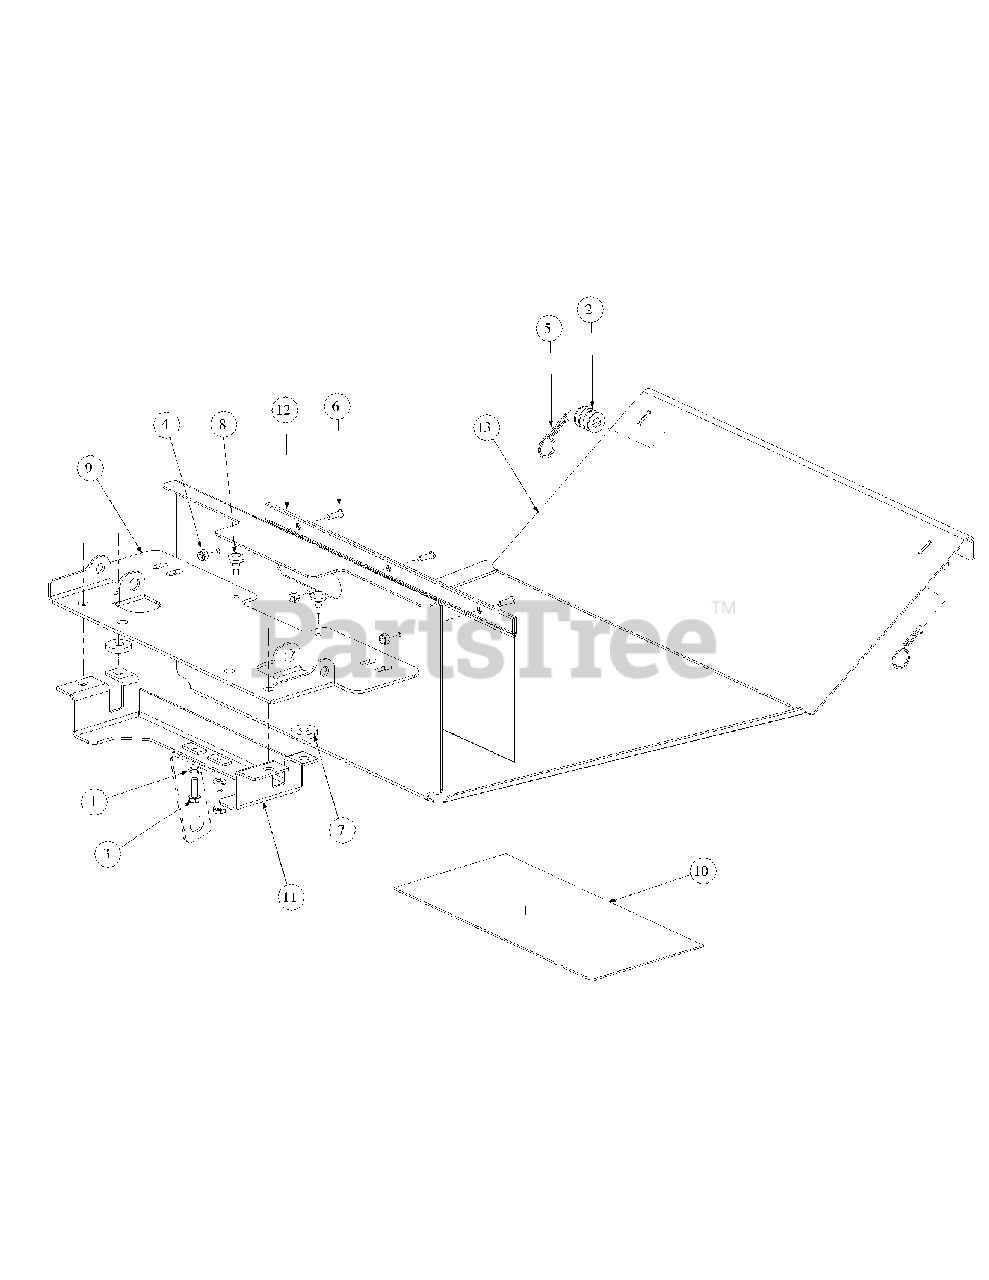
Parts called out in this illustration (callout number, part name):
1	Lock Washer, 1/4
3	Hex Cap Screw, 1/4-20, .75
4	Lock Nut, Nylon Insert, 10-32
5	Hair Pin, 3/8-1/2
6	Screw, Phillips Head, Machine, 10-32 x 5/8
7	Washer
8	Rubber Bumper, .62 OD x .22 Thick
10	Label, Belt Routing and Lubrication
11	Support, Seat Bracket
12	Bag, Debris Storage
13	Floor Panel Assembly
